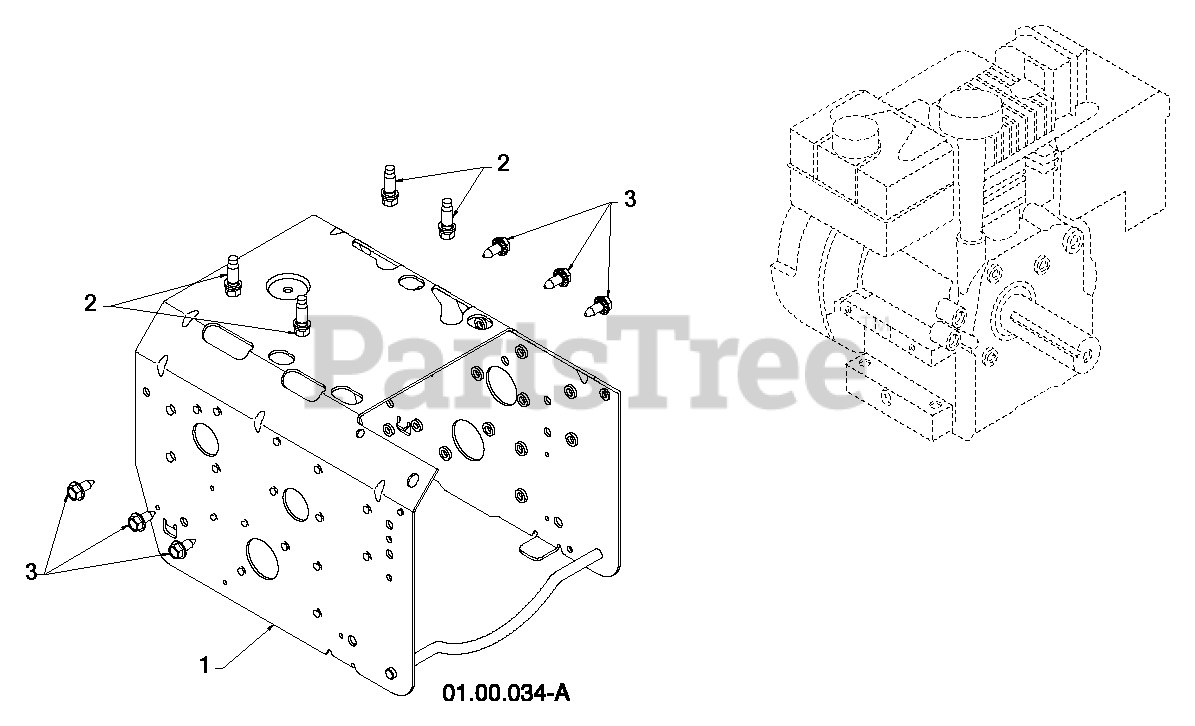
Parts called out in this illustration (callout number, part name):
1	FRAME.WELD.CHAIN.PNT.BLACK
2	BOLT 3/8-16X1-1/8
3	BOLT.HEX.HD.WASHER.5/16-18X.75
